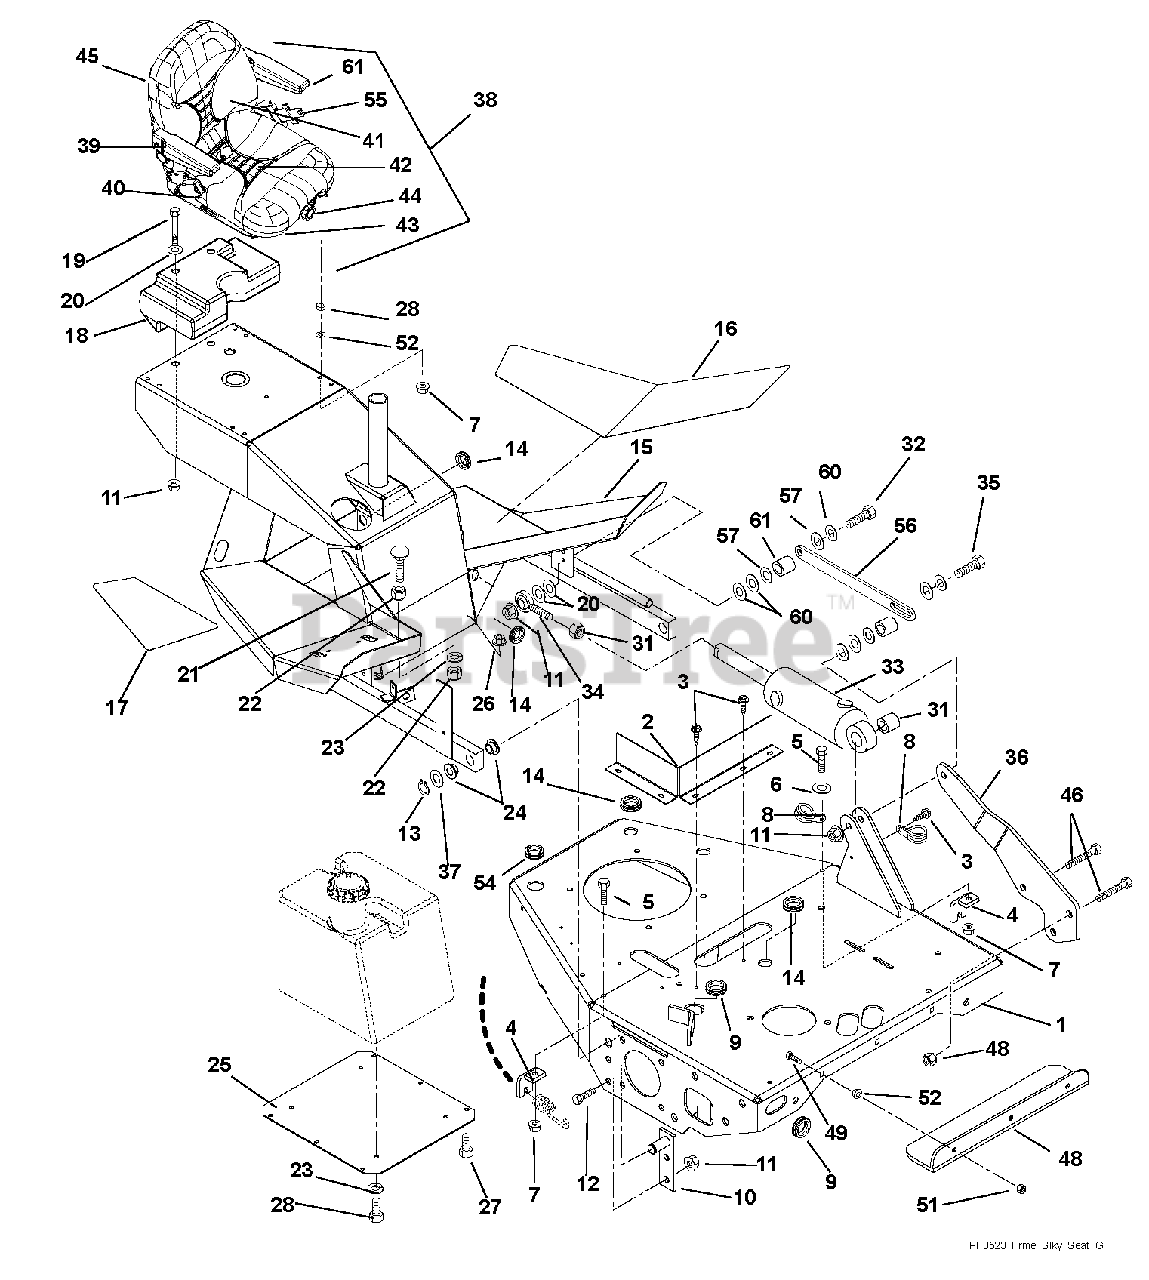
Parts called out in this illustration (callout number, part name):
1	Weldment, Frame
2	Heat Shield
3	Screw, Tapping .25-20 x .50 Hex Washer Head Grade 5
4	Bracket, Cable
5	Bolt, Hex .31-18 x 1.00 Grade 5
6	Washer, Flat Steel .344 x .688 x .065
7	Nut, Locking Top Flange .31-18
8	Clamp, Steel 1.0
9	Grommet 1.25
10	Weldment, Pivot-Sulky
11	Nut, Locking-Top-Flange .50-13 (990024)
12	Bolt, Hex .50-13 x 1.50 Grade 5
13	Ring, Retaining-External .689 x .077
14	Grommet .75 x 1.06 x 1.38
15	Weldment, Sulky
16	Pad, Left Hand Floorboard
17	Pad, Right Hand Floorboard
18	Weight, Rear (990024)
19	Bolt, Hex .50-13 x 2.50 Grade 5 YWZC (990024)
20	Washer, Flat-Steel .531 x 1.06 x .095 (990024)
21	Bolt, Round Head Square Neck .31-18 x 1.50 Grade 5 (990024)
22	Nut, Hex .31-18
23	Washer-Locking .31 x .078
24	Bushing, Flange-Nylon .762 x 1.00 x .58 x 1.48
25	Plate, Bottom
26	Nut, Locking-Top-Flange .38-16
27	Bolt, Hex .38-16 x 1.00 Grade 5
28	Bolt, Hex .31-18 x .75 Grade 5
29	Bushing, Sleeve .377 x .624 x .235
30	Nut, Jam .50-20 Grade 2
31	Bushing, .516 x 1.00 x 1.05
32	Bolt, Hex .50-13 x 2.25 Grade 5 (990024)
33	Cylinder, Platform Lift
34	Assembly, Rod End RH
35	Bolt, Hex .50-13 x 2.75 Grade 5 (990024)
36	Support, Cylinder Brace
37	Washer, Hardened Thrust .758 x 1.23 x .031
38	Seat, Suspension, with Seat Belt, Light Gray
39	Kit, Armrest Assembly RH
40	Kit, Seat Cushion, Light Gray
41	Kit, Seatback Cushion, Light Gray
42	Kit, Spring and Saddle
43	Kit, Seat Slide
44	Kit, Seat Knob
45	Kit, Seat Back Panel
46	Bolt-Hex .62-11 x 1.75 Grade 5
47	Nut-Nylon Locking .625-11
48	Guard, Hose
49	Bolt, Round Head Square Neck .25-20 x .75
50	Nut, Push .312
51	Nut, Locking Top Flange .25-20
52	Nut, Push .250 x .50
53	Kit, Armrest Assembly LH
54	Grommet-2.12 ID Buna-N
55	Kit, Retractable Safety Belt
56	Lever Arm (990025)
57	Washer, Flat Steel .812 x 1.50 x .135 (990025)
58	Washer, 1.25 x .531 x .25 THK (990025)
59	Bolt, Hex .50-13 x 3.50 Grade 5 YWZ (990025)
60	Washer, Flat-Steel .531 x 1.06 x .095 (990025)
61	Bushing (990025)
